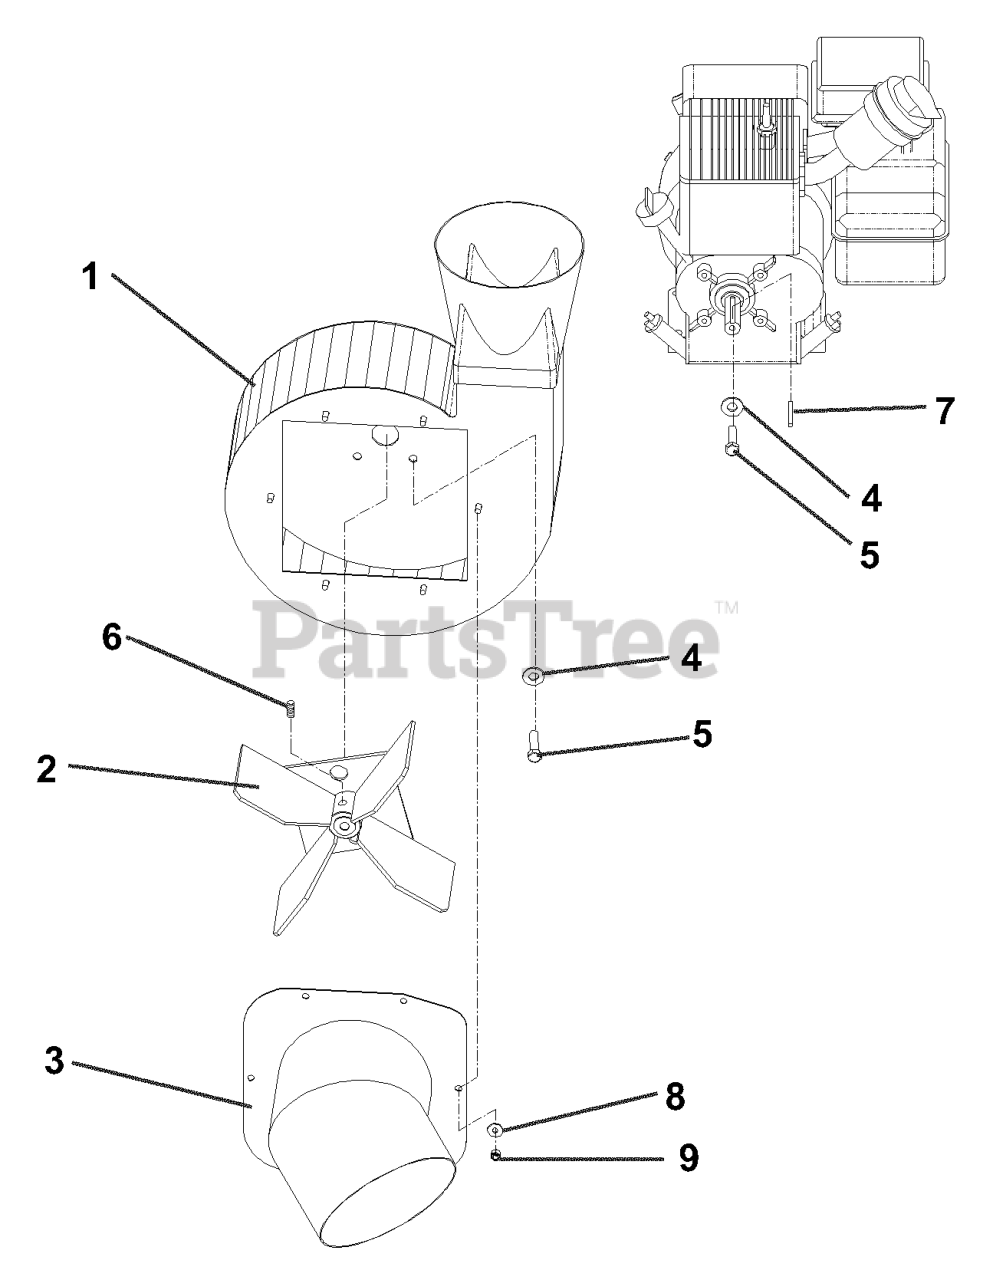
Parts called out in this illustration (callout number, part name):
1	BLOWER HOUSING
2	IMPELLAR
3	BLOWER HOUSING INLET
4	R/B 109600 WASH SPRING, 5/16
5	R/B 990233 BLT HEX 5/16-24X3/4
6	SCREW SET, 3/8-24 X 3/8
7	KEY SQUARE 3/16 X 3/16 X 1 3/4
8	Nut, Hex, Nylon Lock, 1/4"-20
9	Washer, Flat, 1/4"
